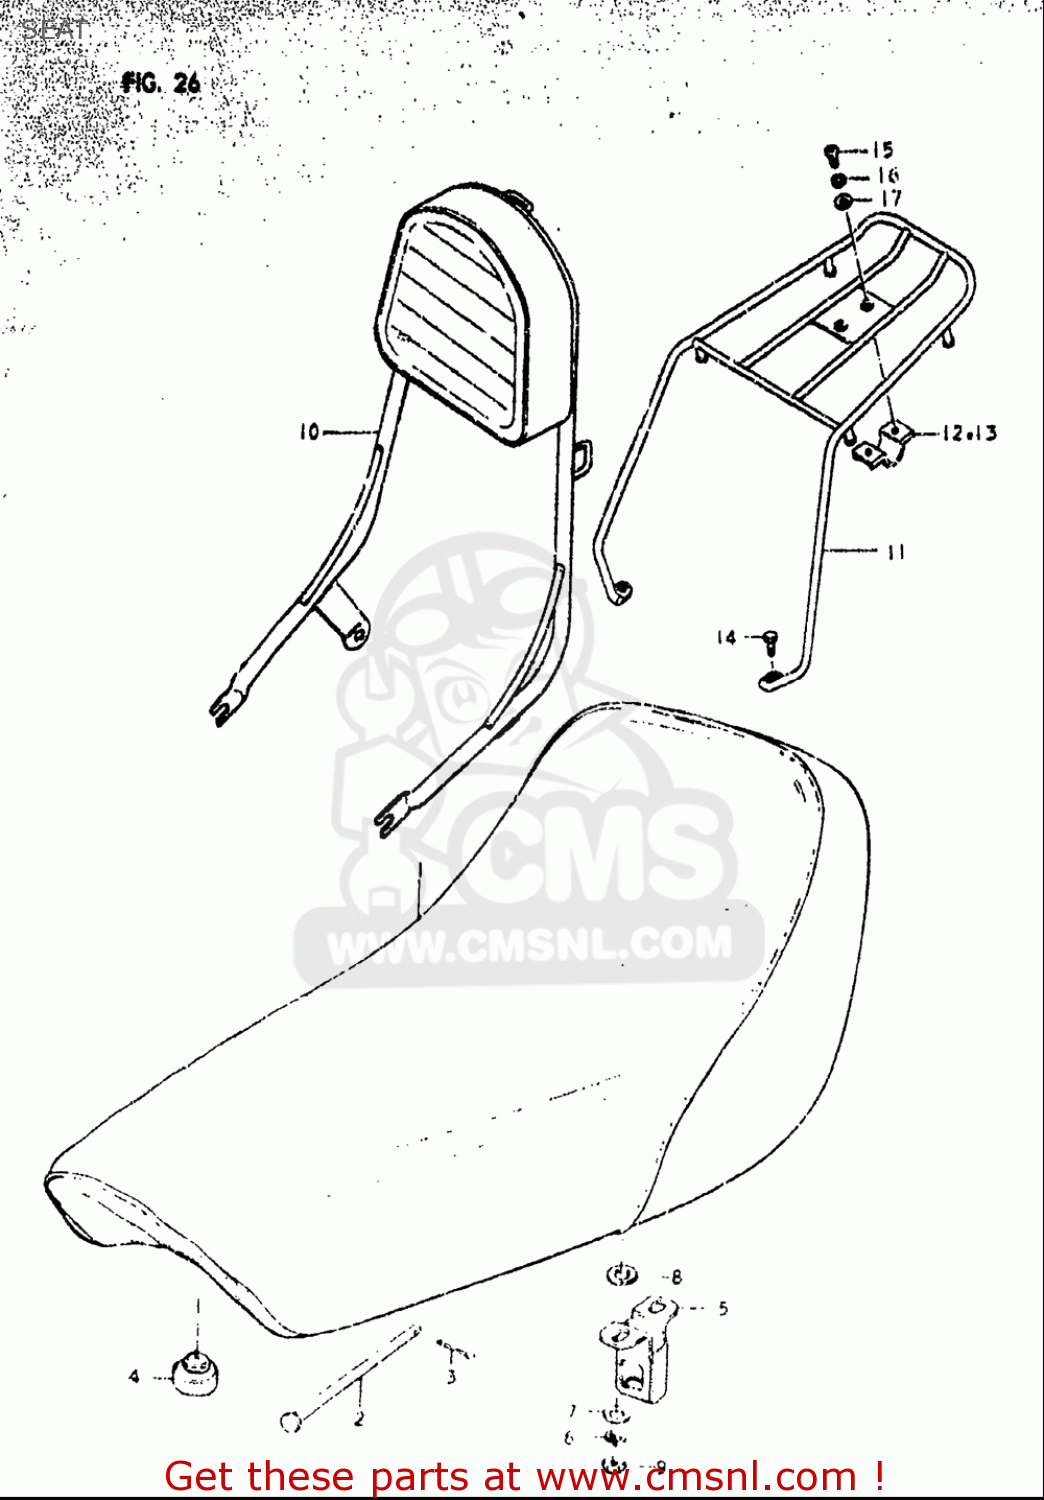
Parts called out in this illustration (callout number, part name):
3	PIN
4	CUSHION(11.5X22X20)
5	STRIKER,SEAT LOCK
6	WASHER,LOCK
7	WASHER
8	WASHER
9	NUT
14	BOLT
15	SCREW
16	WASHER,LOCK
17	WASHER
